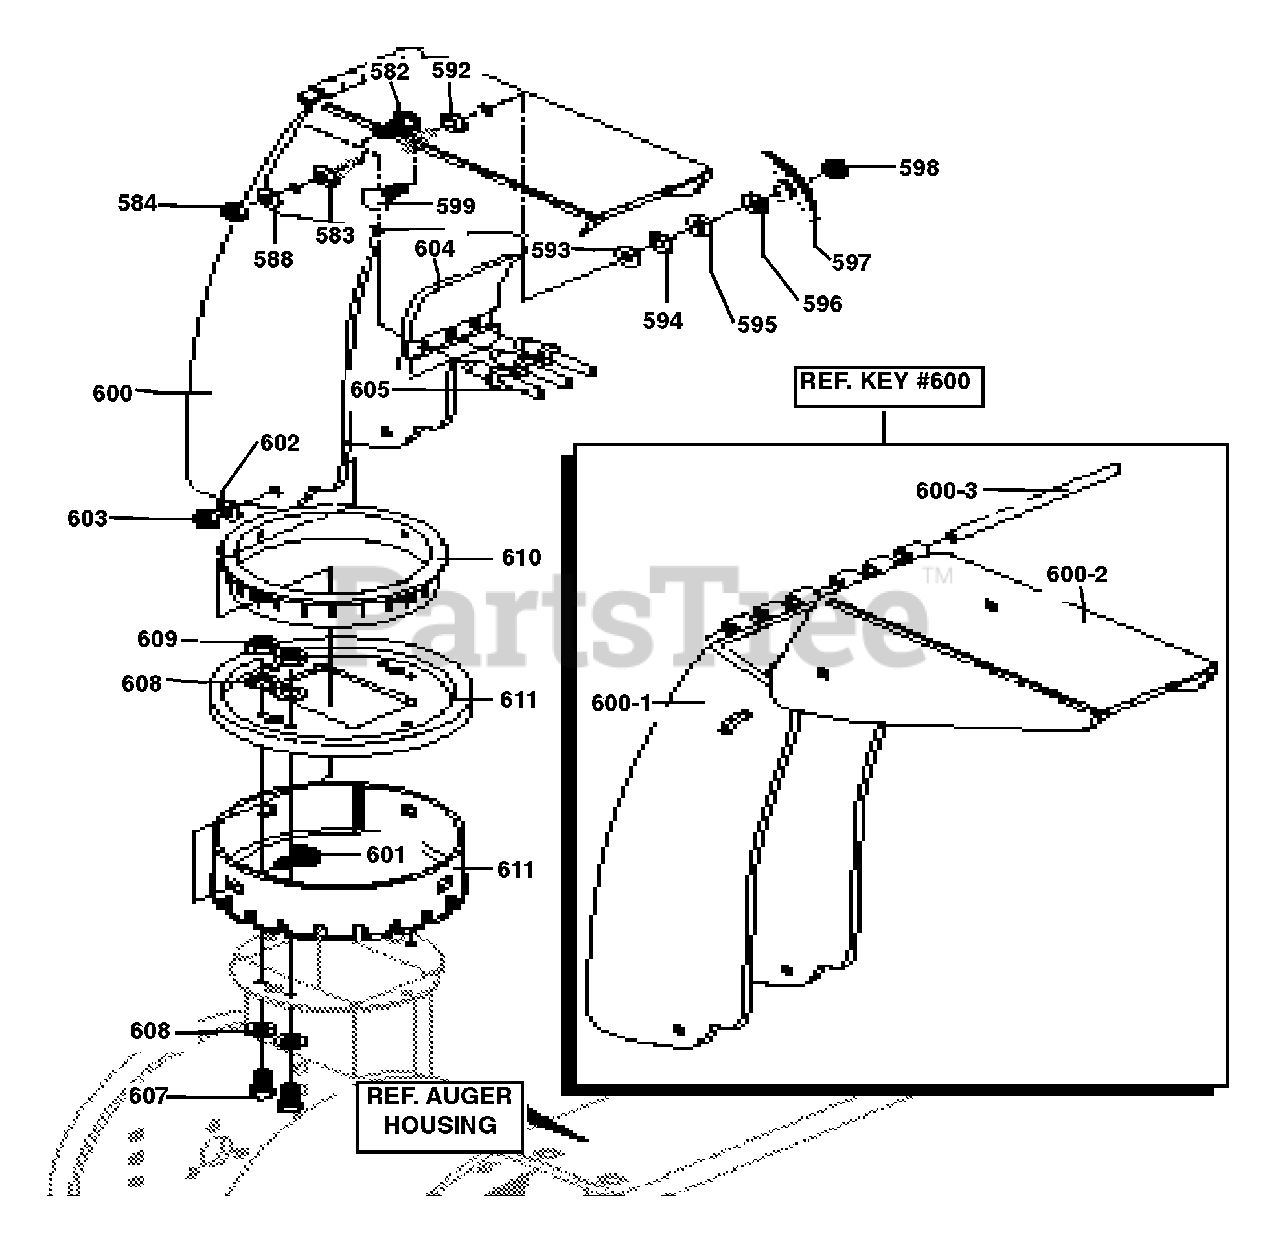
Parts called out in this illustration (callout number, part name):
582	Bolt, 5/16-18 x .75
583	Washer, Pl .438 x .75 x .064
584	Nut, 5/16-18
588	Washer, .315 x .75 x .064
592	Washer, Pl .438 x .75 x .064
593	Washer, .315 x .75 x .064
594	Flatwasher .344 x .69 x .065
595	Washer, .328 x .60 x .09
596	Flatwasher .344 x .69 x .065
597	Knob, T
598	Nut, 5/16-18 Reghex
599	Bolt, Carr. 5/16-18 x 1.00
600	Chute Assembly
600-1	Lower Chute
600-2	Upper Chute
601	Bolt, 5/16-18 x 1.00
602	Flatwasher, .344 x .69 x .065
603	Nut, 5/16-18 Hexnyl
604	Flap, Chute Inset Assy
605	Included in 604 assembly
606	Collar, Chute
607	Screw, 1/4-20 x .75
608	Flatwasher, .281 x .63 x .065
609	Nut, 1/4-20 Reghexctrlk
610	Retainer, Ring Inner
611	Retainer, Ring Outer
